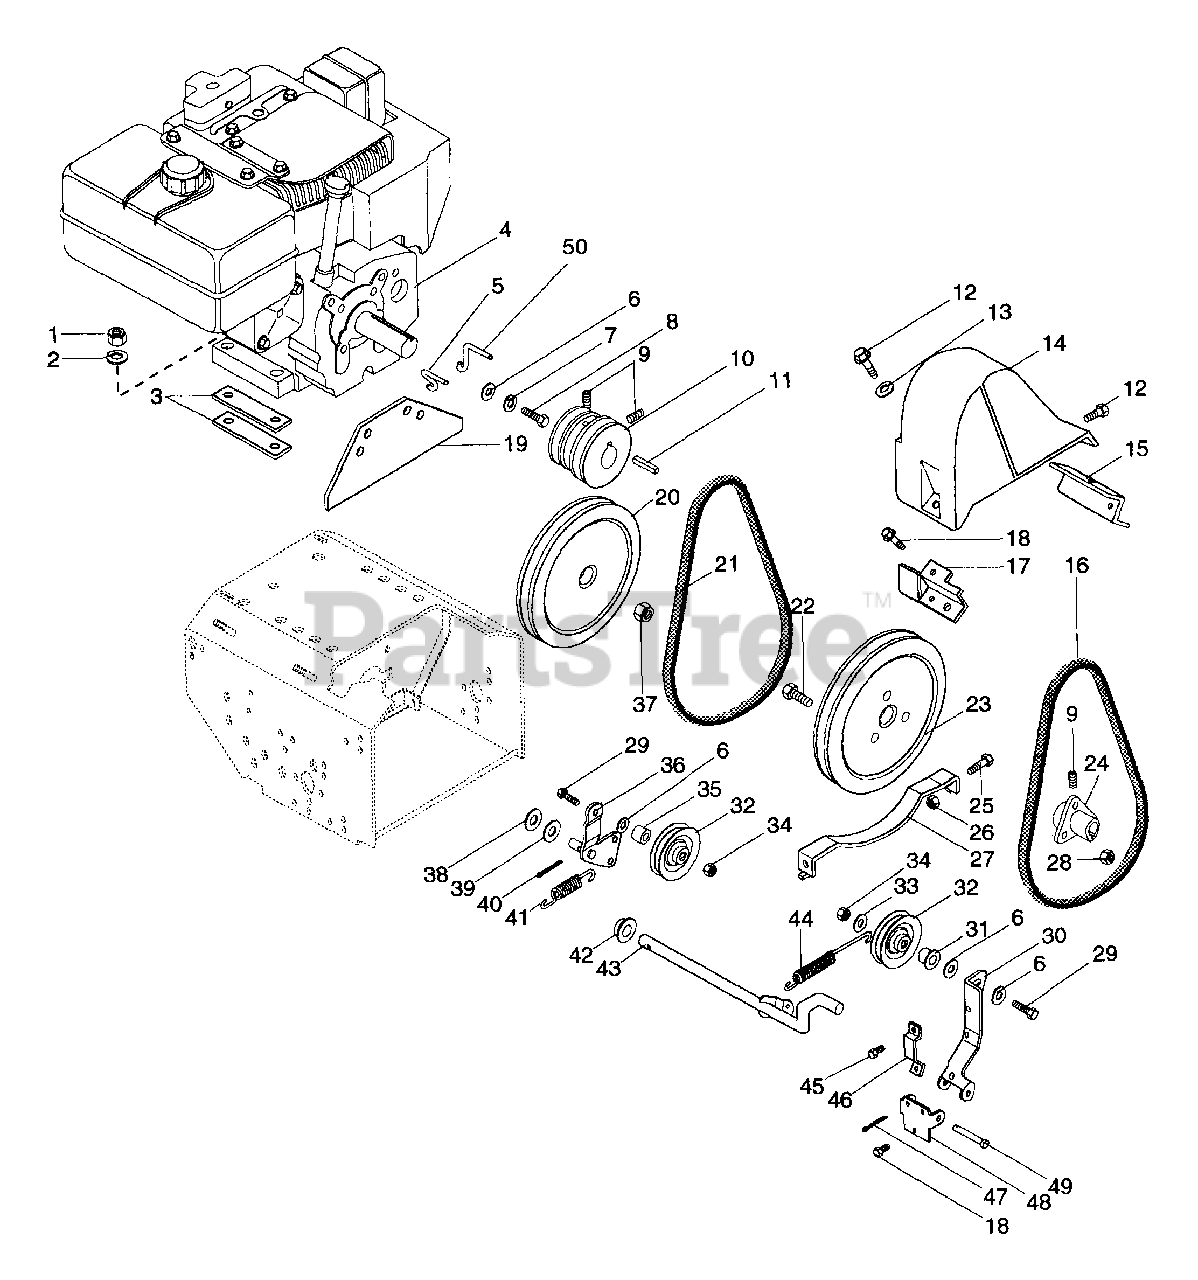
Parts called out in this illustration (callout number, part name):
1	NUT-HEX .312-18
2	WSHR-LK .312X.097 PL HVY
2	WSHR-LK-INT .313X.030 PL
3	STRAP
4	ENGINE-TEC HMSK80 ISO
4	ENGINE TEC HMSK10 18W/ALT ISO
4	ENGINE-TEC OHSK120 18W/ALT ISO
4	ENGINE-TEC OHSK120 12VDC ISO
4	ENGINE - TEC HMSK 90 ISO
5	BELT FINGER
6	WSHR-FL-STL .38X.875X.083 PL
7	WSHR-LK-EXT .313X.030 PL
8	BLT-HEX .31-24X.75 PL GR5
9	SCR-SET .31-18X.38 SKHCUPDL
10	SHEAVE, ENGINE
11	KEY-STR .25X1.75X.25
12	SCR-TAP .250-20X.50 HXSLHDPL
13	WSHR-FL-STL .268X.562X.046 PL
14	BELT COVER
15	L.H. SUPPORT
16	V-BELT, 4L-RAW EDGE
17	R.H. SUPPORT
18	SCR-TAP .250-20X.37 HWH PL TR
19	PLATE
20	PLY-V 8.00 X 1.0 W/KEY CLARK
21	V-BELT, 3L-RAW EDGE
22	BLT-SERRDHD SL .31-18X.87 PL
23	PLY-V 9.0 X 1.25 3BLT
25	BLT-HEX .25-20X.50 PL GR2
26	NUT-LK-CTR .250-20 PL
27	BELT RETAINER
28	NUT-FLG. .312-18 PL
29	BLT-HEX .31-18X1.25 PL GR2
30	ARM, IDLER
31	SPCR, BRG .315X.50X.688X.281
32	IDLER
33	WSHR-FL-STL.312X.734X.065PL
34	NUT-LK .312-18 GR A PL
35	SPACER .50 X .32 X .42
36	IDLER ARM
37	NUT-LK-NYL.625-18 PL
38	WAVE WASHER .406X.750X.063FH
39	WSHR-FL-STL .382X.812X.023 PL
40	PIN-COTR .12X1.0 PL
41	SG-TENS .080X.73X3.06 WLD 20
42	BSHG-FLG.500X.625X.312X.750NY
43	ACTIVATING SHAFT
44	SG-TENS .047X.44X3.37 WLD 1.47
45	SCR-TAP 10-24X.375 HWH PL TR
46	RETURN CLIP
47	PIN COTR .09X.50 PL
48	BRACKET
49	PIN-CLEV .309X2.25
50	BELT FINGER
